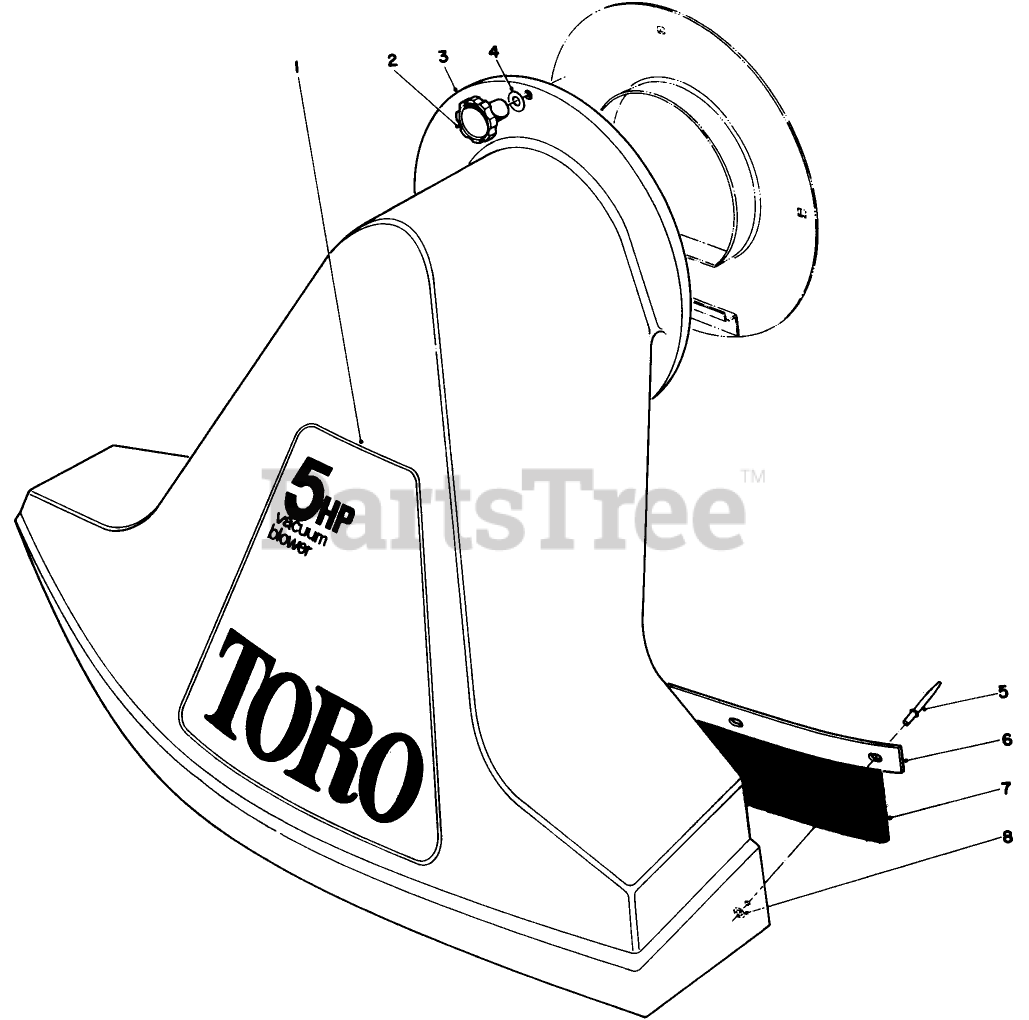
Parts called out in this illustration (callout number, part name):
3	SNOUT ASM
5	POP RIVET 3/16X.375LG
7	FLAP-RUBBER
8	WASHER-FLAT
